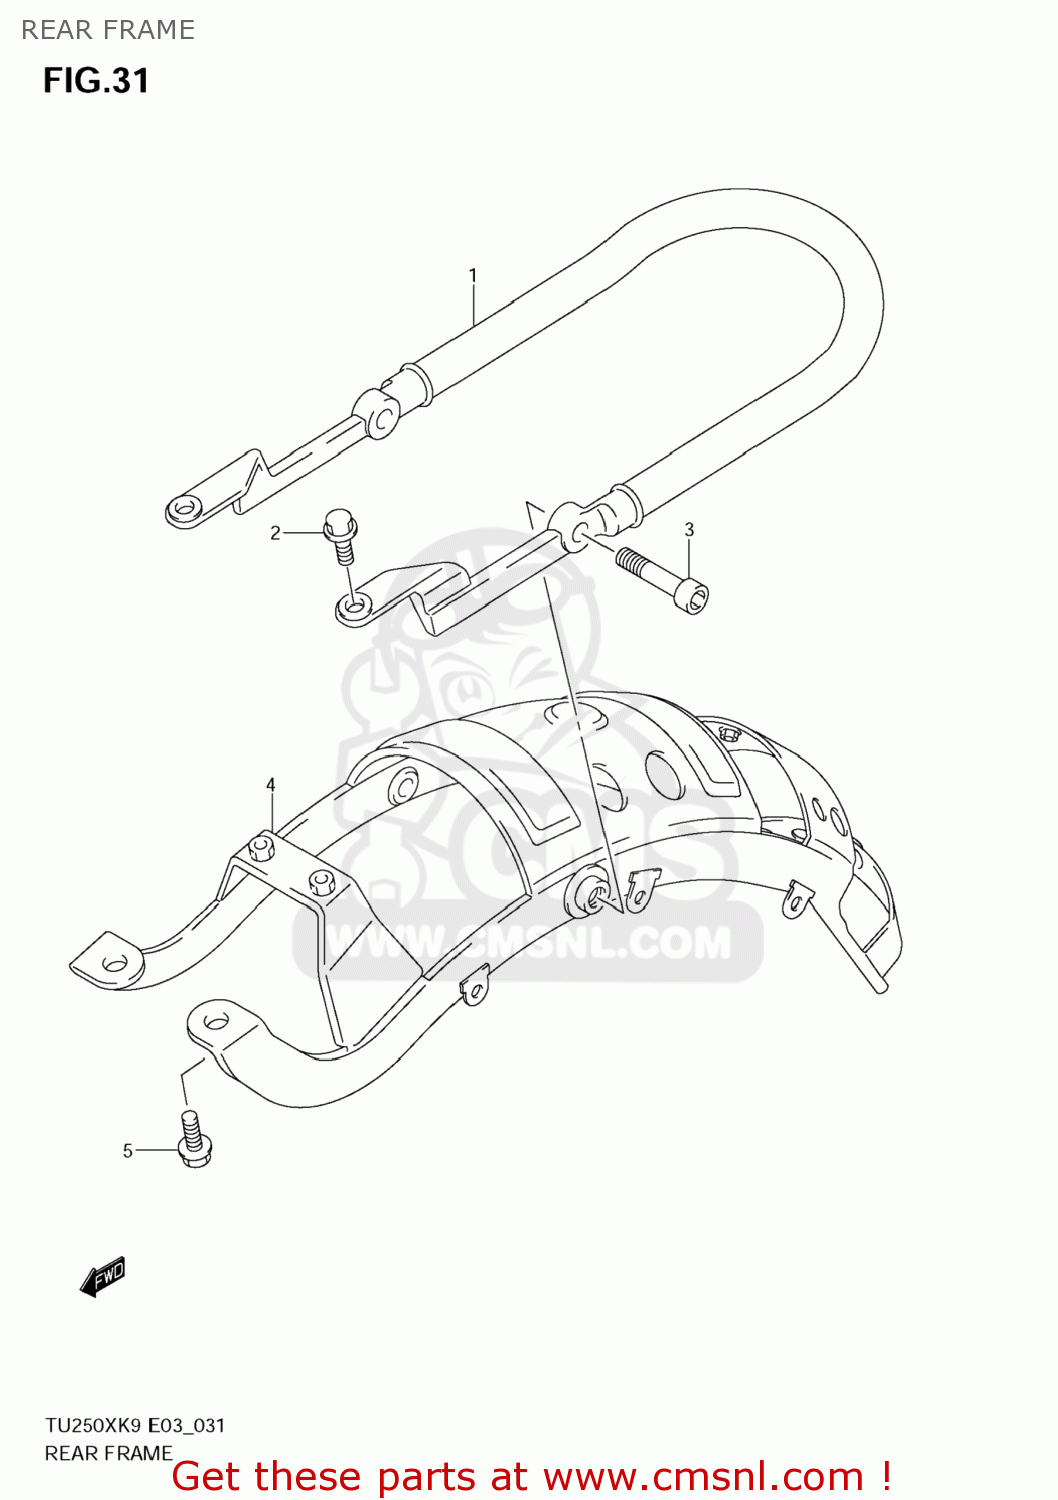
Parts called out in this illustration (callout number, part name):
1	FRAME,RR(SILVER)
2	BOLT(8X25)
3	BOLT(12X45)
4	BRACE,RR FRAME
5	BOLT
